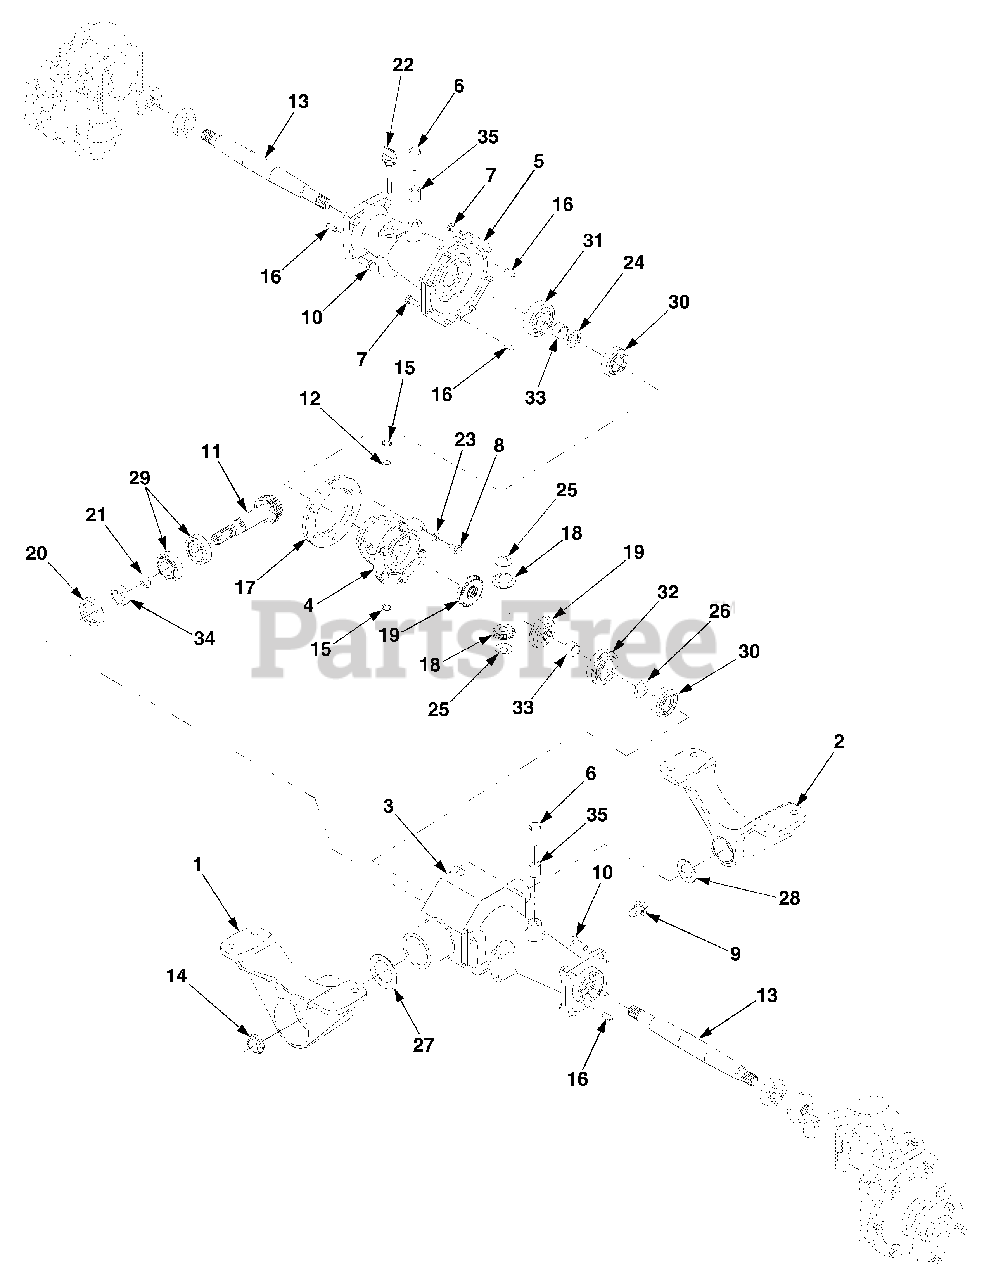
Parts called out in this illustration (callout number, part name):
1	Bracket, Front Axle Mtg. - Rear
1	Fitting, Lube, 1/4-28
1	Bearing, Sleeve
2	Bracket, Front Axle Mtg. - Front
2	Fitting, Lube, 1/4-28
2	Bearing, Sleeve
3	Housing, Main Axle RH
4	Housing, Differential
5	Housing, Axle LH
6	Screw, Hex Cap, M10-1.5 x 35 GR8.8
7	Screw, Hex Cap, M8-1.25 x 25 GR8.8
8	Screw, Hex Cap, M8-1.25 x 14 GR8.8
9	Plug, Screw, M14-1.5 x .827
10	Screw, Hex Cap, M10-1.5 x 25
11	Shaft, Input, 11T
12	Shaft, Cross
13	Shaft, Axle
14	Nut, Special, 24mm
15	Ring, Retaining
16	Pin, Dowel, 8mm x 20mm
17	Gear, Bevel, 35T
18	Gear, Miter, 10T
19	Gear, Miter, 16T
20	Seal, Oil, 52mm x 35mm x 10mm ..
21	O-Ring, 19mm x 3mm
22	Dipstick, Front Axle, includes:
23	Washer, Flat, .33 x .63 x .0635
24	Washer, Flat, .793 x 1.24 x .06 Hdn.
25	Washer, Special Spherical
26	Washer, Flat, .793 x 1.37 x .005
27	Washer, Thrust, 1.66 x 2.59 x .059
28	Washer, Thrust, 1.03 x 1.73 x .059
29	Bearing, Tapered Roller w/ Race ...
30	Bearing, Ball
31	Bearing, Ball
32	Bearing, Ball
33	Spacer, 20 x 25 x 16mm
34	Spacer, 25 x 35 x 12mm
35	Spacer, .5 x .75 x .86
